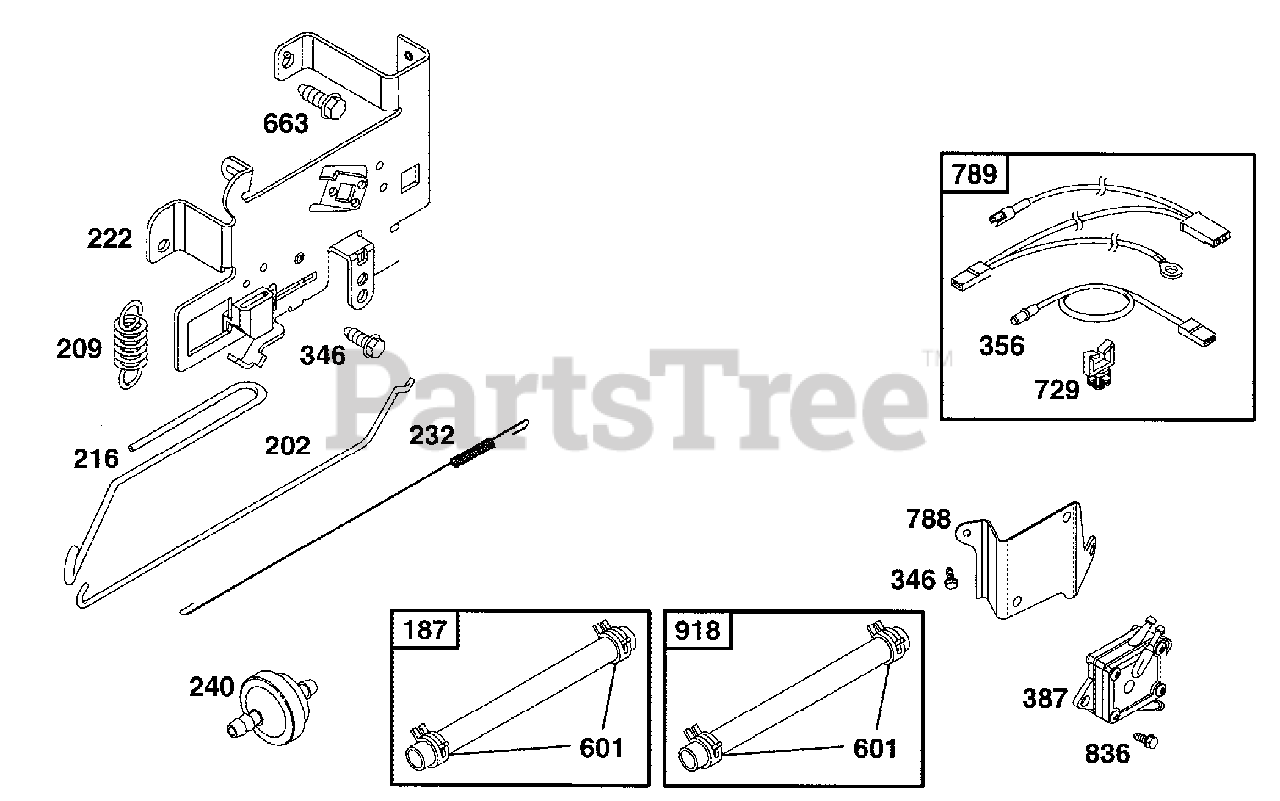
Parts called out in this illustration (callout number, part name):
187	Fuel Line
202	Mech. Governor Link
209	Governor Spring
216	Choke Link
222	Control Bracket
232	Link Spring
240	Fuel Filter
346	Hex Screw
387	Fuel Pump
601	Hose Clamp
663	Hex Screw
788	Pump Bracket
789	Wiring Harness
836	Hex Screw
918	Vacuum Hose
